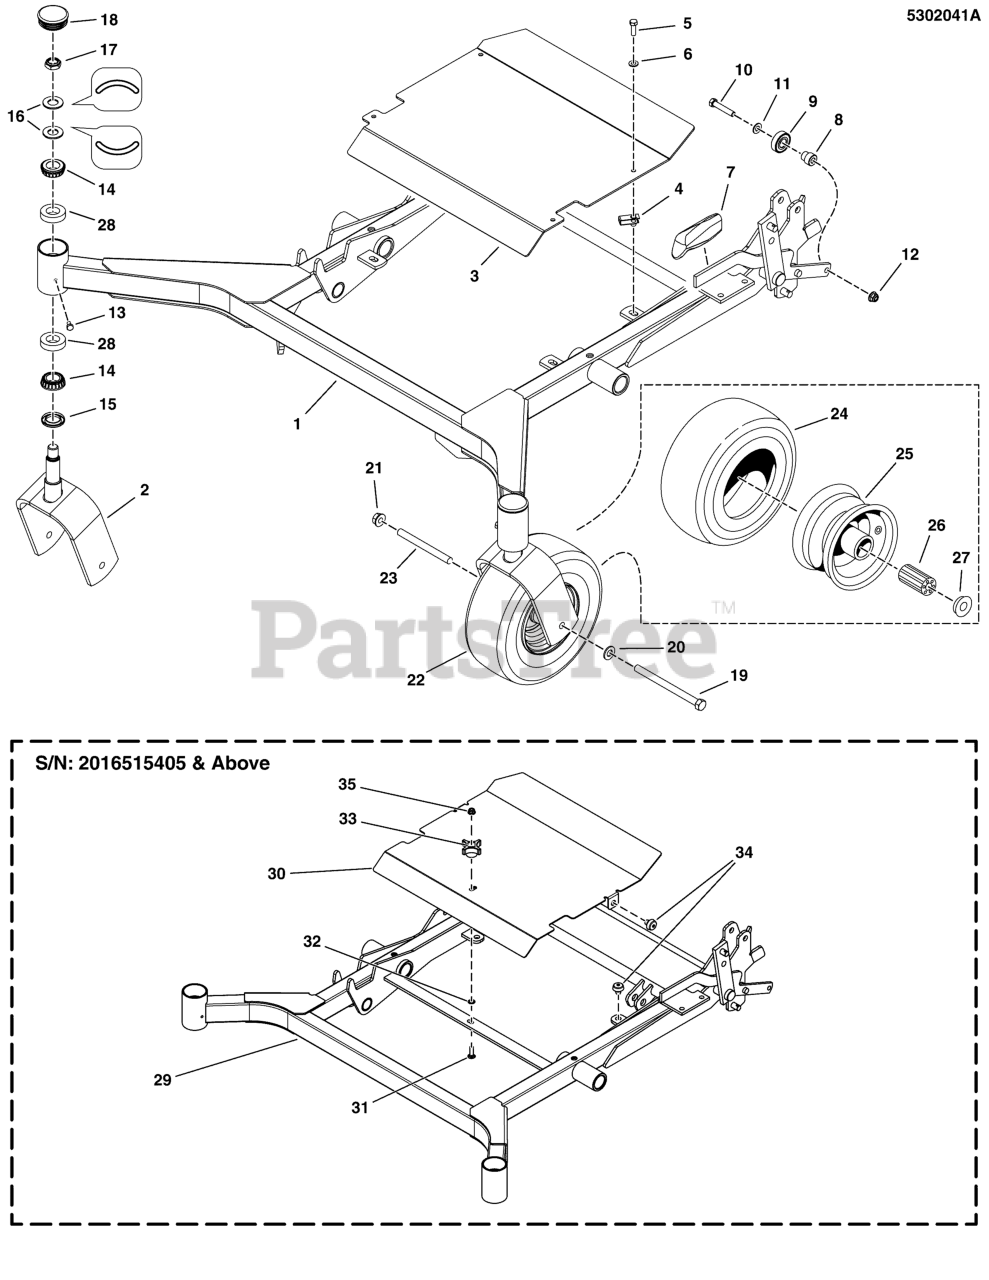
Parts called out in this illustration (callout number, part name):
1	WELD, MOWER FRAME - OUTFRONT - RED
2	WELD., FRONT CASTER YOKES - RED
3	DECK GUARD, CENTER, 72 - RED
4	BODY CLIP, 5/16-18 -1/4 MATERIAL
5	BOLT, 5/16-18 X 1" GRD5 YZ
6	WASHER, 5/16" SAE
7	GRIP, BLACK FLEXIBLE
8	SPACER, HYDRO PULLEY
9	BEARING, BALL 11/16X1-9/16X15/32
10	BOLT, 3/8-16 X 2, GD5, CZ
11	WASHER, 3/8 SAE
12	NUT, 3/8 - 16 HEX NYLOCK FLANGE
13	BOLT, 1/4-28 X 1/2, GD5 YZ
14	BEARING, TAPERED ROLLER, 1"
15	SEAL, GREASE
16	WASHER, BELLEVILLE - 1.500 X .755
17	NUT, 3/4-16, HEX JAM NYLON LOCK
18	CAP, GREASE, LOW PROFILE
19	BOLT, HEX, 1/2-13 X 7, GD 8, YZ
20	WASHER, 1/2 SAE
21	NUT, Hex Flange, Nylock, 1/2-13
22	WHEEL, CASTER, 11 X 4.0-5 SILVER BEAD LO
23	AXLE, Front Caster
24	TIRE, FRONT, 11 X 4.0 - 5 (SV)
25	WHEEL FOR 11X4.0-5 TIRE ASSM
26	BEARING, CASTER WHEEL, 11 X 4.0 - 5 BEAD LOCK (SV)
27	RETAINER, BEARING (TWO PER TIRE)(SV)
28	CUP, BEARING (SV)
29	WELD, MOWER FRAME, 800, 72 - RED
30	DECK GUARD, CENTER, 800, 61" - RED
31	BOLT, 5/16-18 X 1, CARRIAGE, GD5, CZ
32	5/16" PUSH-ON NUT RETAINER, STL, CZ
33	KNOB-INT THR .312-18 4-ARM 2.12WD 1.06LG
34	MNT, VBRTN, RBBR
35	NUT, 5/16-18 HEX NYLOCK FLANGE NUT
